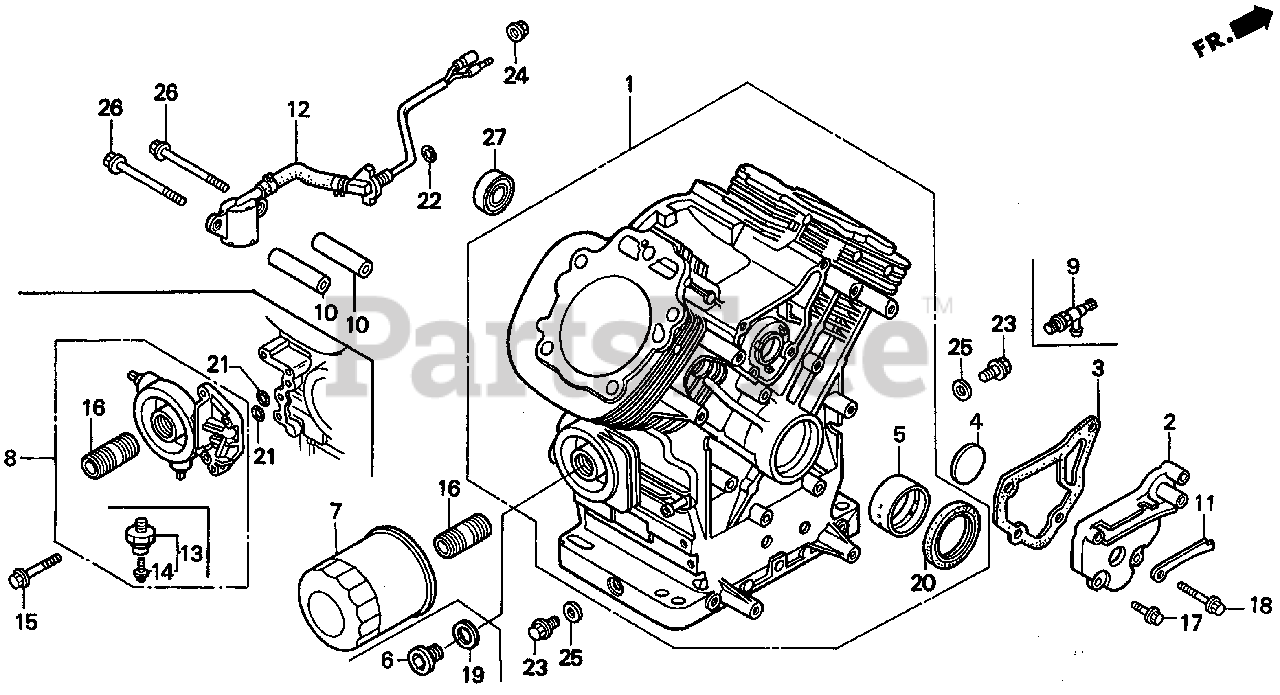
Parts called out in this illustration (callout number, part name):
1	CYLINDER ASSY.
2	COVER, BREATHER
3	GASKET, BREATHER COVER
4	VALVE, BREATHER
5	BEARING A, MAIN (TO SELECT CORRECT BEARING, SEE THE SERVICE MANUAL.)
5	BEARING B, MAIN (TO SELECT CORRECT BEARING, SEE THE SERVICE MANUAL.)
5	BEARING C, MAIN (TO SELECT CORRECT BEARING, SEE THE SERVICE MANUAL.)
7	FILTER, OIL (SOLD INDIVIDUALLY)
7	FILTER, OIL (SOLD IN MULTIPLES OF 30)
9	VALVE, DRAIN (14X1.5)
11	CLAMP, WIRE
16	HOLDER, OIL FILTER
17	BOLT, FLANGE (6X16)
18	BOLT, FLANGE (6X32)
20	OIL SEAL (38X58X11)
23	BOLT, DRAIN PLUG (14MM)
25	WASHER, DRAIN PLUG (14MM)
27	BEARING, RADIAL BALL (6003)
